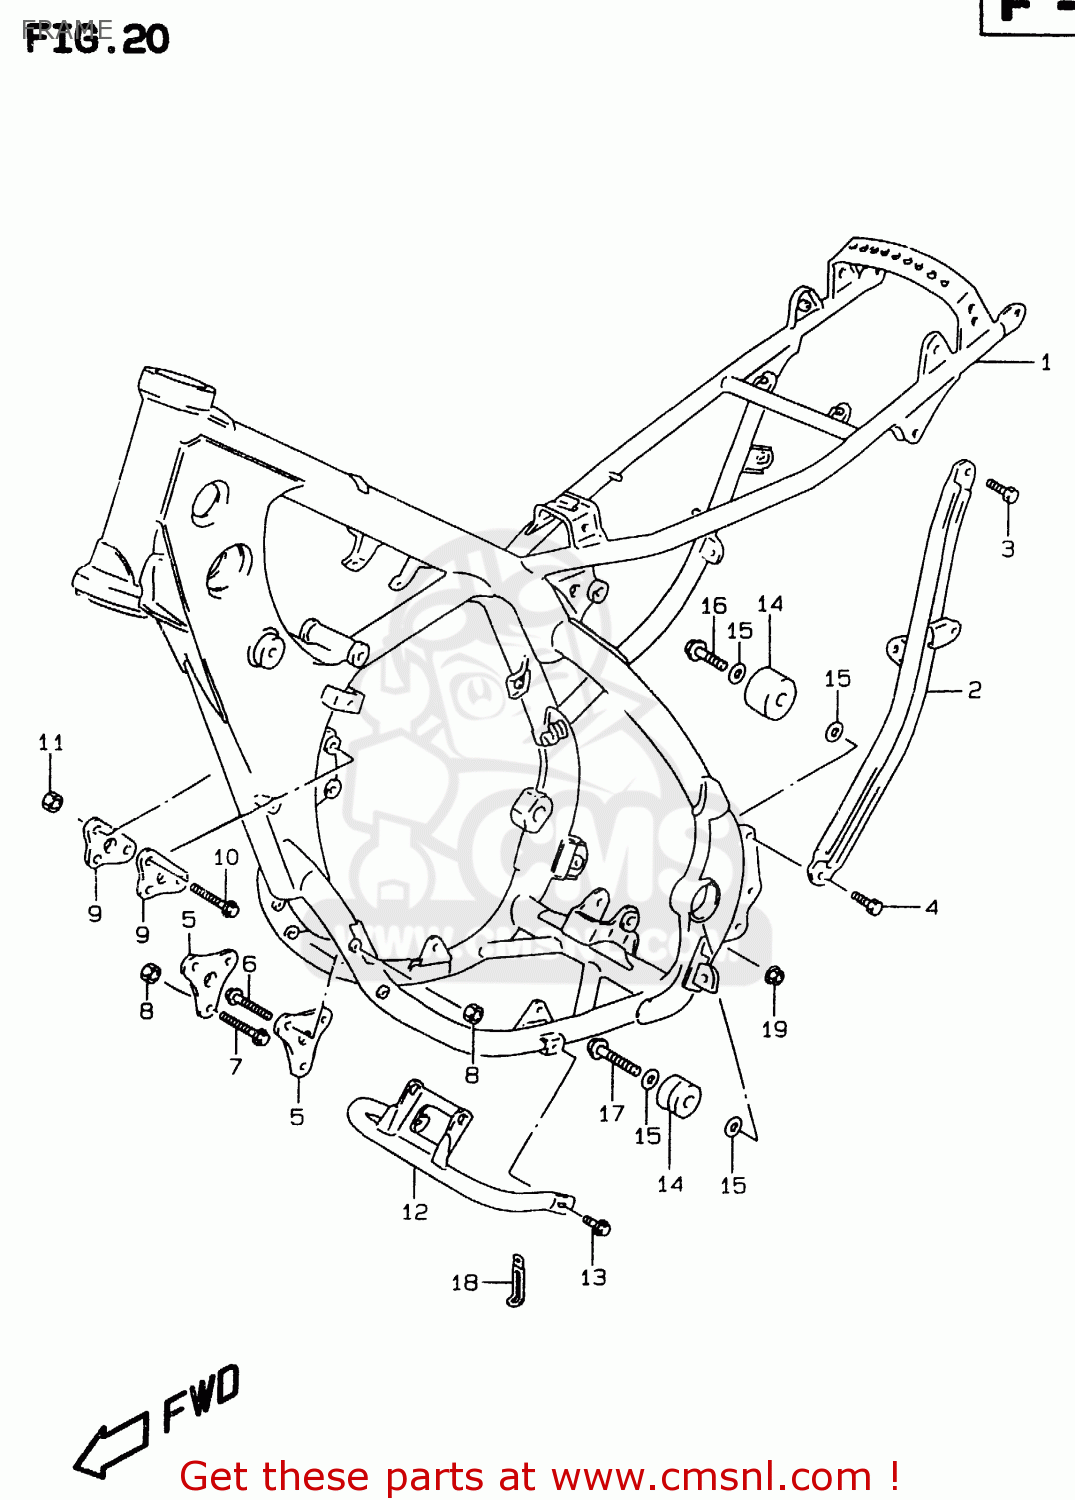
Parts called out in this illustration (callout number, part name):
1	FRAME COMP
2	TUBE,FRAME SIDE,L
3	BOLT
4	BOLT
5	PLATE,ENG MTG FR
6	BOLT
7	BOLT M8X65
8	NUT
9	PLATE,ENGINE MOUNT UPR
10	BOLT(8X45)
11	NUT
12	PROTECTOR,ENGINE
13	BOLT(8X14)
14	ROLLER,CHAIN
15	SHIM(8X12X1)
16	BOLT(8X41)
17	BOLT(8X45)
18	CLAMP(L:65)
19	NUT
